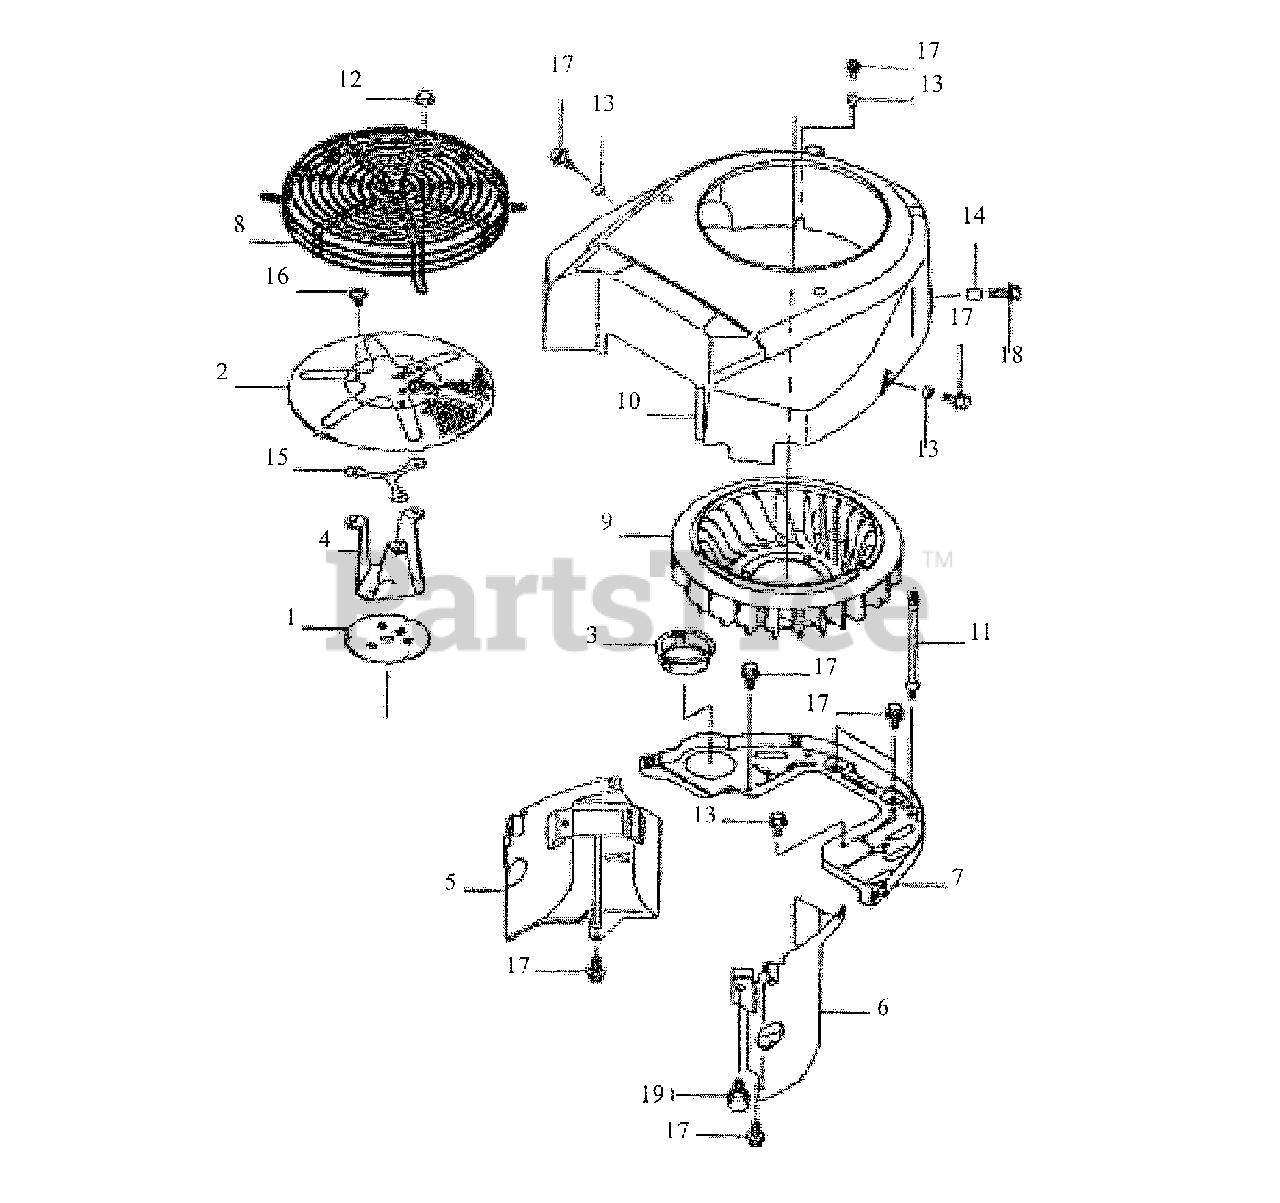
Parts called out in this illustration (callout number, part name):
4	Bracket-Comp
5	Shroud-Engine
6	Shroud-Engine
7	Shroud-Engine
8	Guard
11	Stud
12	Nut
13	Spacer 6.2 x 7.9 x5
14	Spacer 6.5x7.9x10.5
16	Bolt, 6 x 10 mm
17	Bolt Flange
18	Bolt Flange
19	Bolt Flange
